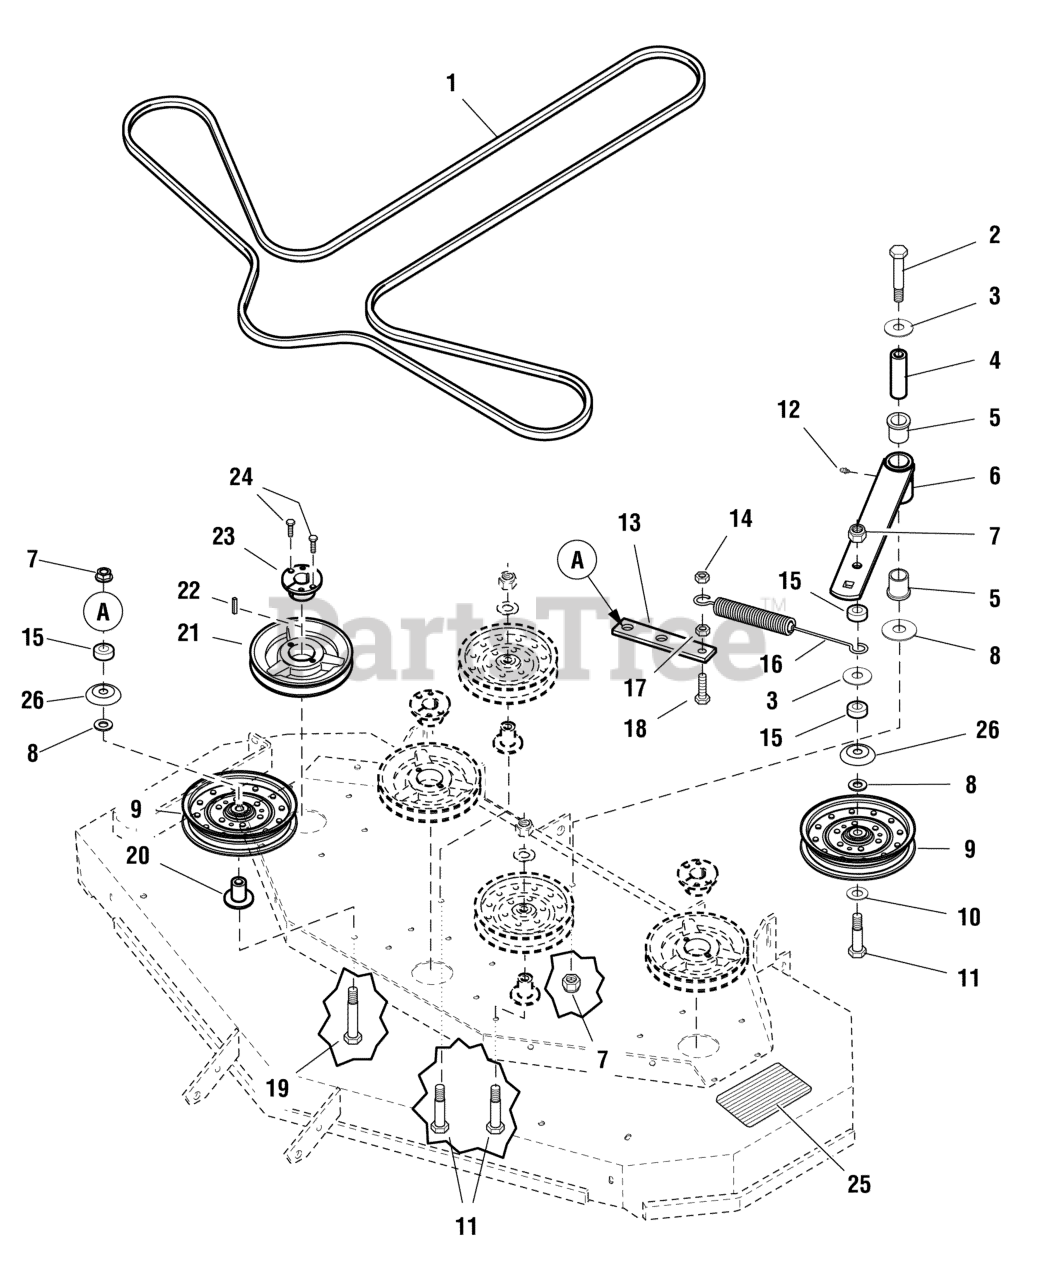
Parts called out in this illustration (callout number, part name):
1	BELT, 5V, 175.90EL, LG ARAMID, WRPD, RC
2	BOLT, 1/2-13 X 4-1/2" GD5 YZ
3	WASHER, 1/2" USSZ
4	SPACER, .52 x 1.00 x 3.50
5	BUSHING, FLANGE
6	WELD, IDLER ARM (10.50)
7	NUT, 1/2-13 HEX NYLON LOCK
8	WASHER, 1/2 SAE
10	WASHER, 1/2 SAE
11	BOLT, 1/2-13 X 3" GD5 CZ
12	GREASE FITTING, 1/4-28 Straight
13	MOUNT, Idler Spring
14	NUT, 3/8 - 16 HEX NYLOCK FLANGE
15	SPACER, .52 X 1.00 X .44, CZ
16	SPRING-EXT, 1.04 ODX10.535LGX.148WR, BLK
17	NUT, 3/8-16 HEX, YZ
18	BOLT, 3/8-16 X 1-1/4" GD5 CZ
19	BOLT, 1/2-13 X 3-1/2, HEX HD, GD5, CZ (SV)
20	IDLER MOUNT
21	PULLEY, SPINDLE, BH66
22	KEY 1/4 SQ X 1 1/2 LONG
23	BUSHING, Tapered Hub
24	BOLT, 1/4-20 X 1" GD5 CZ
25	SAFETY WALK, 4.00 X 7.50
26	SHIELD, PULLEY BEARING, CZ
